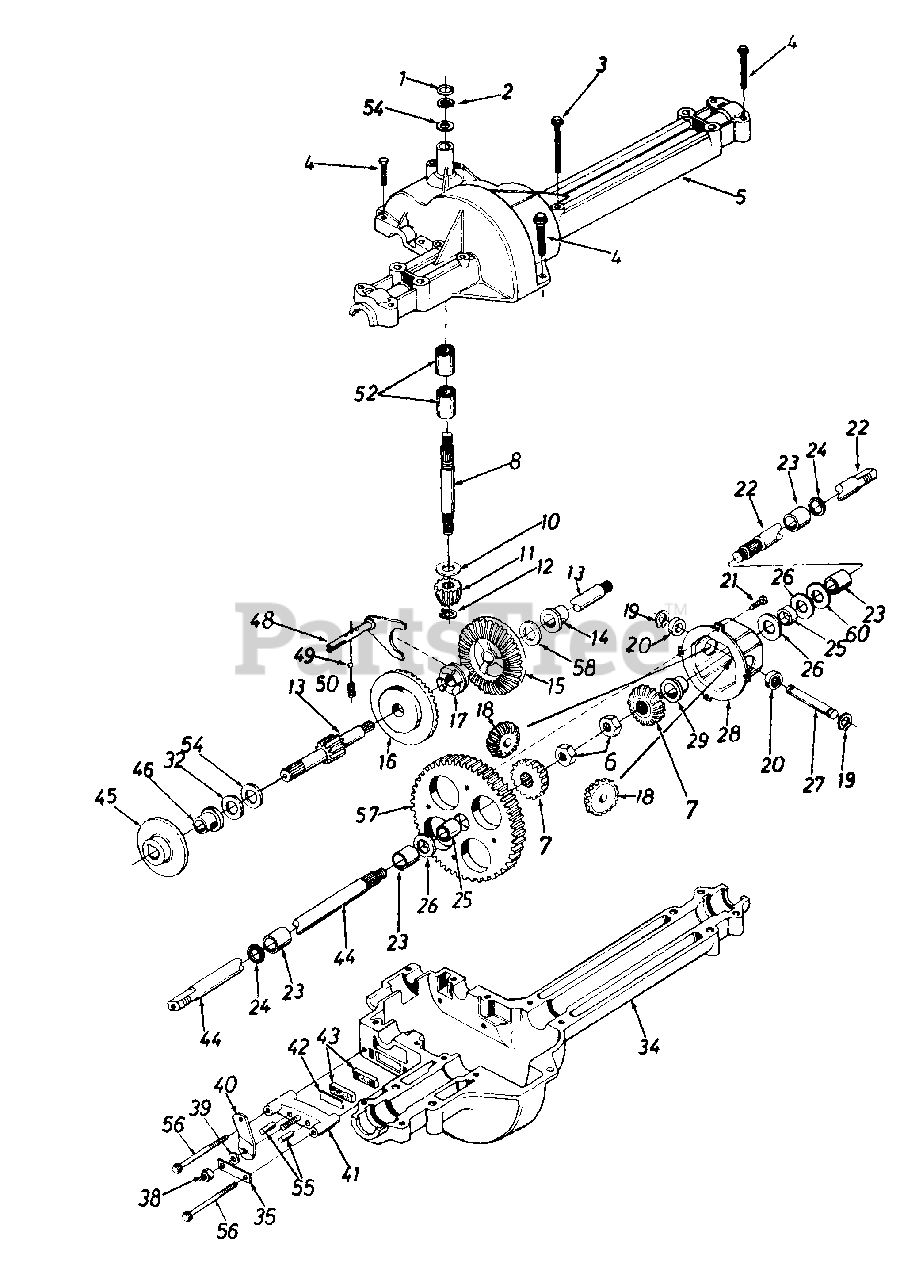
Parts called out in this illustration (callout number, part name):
1	Wire Ring
2	Retaining - Ring
3	Hex Bolt 1/4-20 x 1.75" Lg.
4	Hex Tap Scr. 1/4-20 x 1.25" Lg.
5	Upper Housing
8	Input Shaft
10	Thrust Washer 5/8" I.D. x 1.25" O.D.
11	Pinion Input 14T
12	Retaining Ring
13	Drive Shaft - L.H. Brake
14	Flange Brg. 5/8" I.D. x 3/4" Lg.
15	Bevel Gear 427 Small I.D.
16	Bevel Gear 42T Large I.D.
17	Clutch Collar
18	Miter Gear 15T (H.D.)
19	Retaining Ring
20	Thrust Bearing
21	Pan Head Scr. 1/4-20 x .50" Lg. w/Patch
22	Axle R.H. Ass'y.
23	Sleeve Bearing 3/4" I.D. x 1.0" Lg.
24	Oil Seal 3/4" I.D.
25	Axle Spacer
26	Fl-Wash..760" I.D. x 1.8" O.D.
27	Cross Shaft
28	Differential Can Ass'y.
32	Washer (See Below)
34	Lower Housing
35	Anti-Rotation Brkt.
38	Hex Nut 5/16-24 Thd.
39	Fl-Wash..344" I.D. x .875" O.D.
40	Actuating Arm
41	Brake Yoke
42	Puck Plate
43	Brake Puck
44	Axle L.H. Ass'y.
45	Brake Disc
46	Flange Bearing 5/8" I.D. x 15/16" Lg.
48	Shift Fork Ass'y.
49	Ball Detent .250" Dia.
50	Spring Detent
52	Needle Brg. 5/8" I.D. x 1/2" Lg.
54	Fl-Wash. 5/8" I.D. x 1" O.D. x .020 Thk.
55	Actuating Pin 5/16" Dia.
56	Hex Wash Hd. Self-Tap Scr. 1 4-20 Thd.
57	Differential Gear 58T
58	Fl-Wash. 5/8" I.D. x 1" O.D. x .020 Thk.
60	Washer (See Below)
